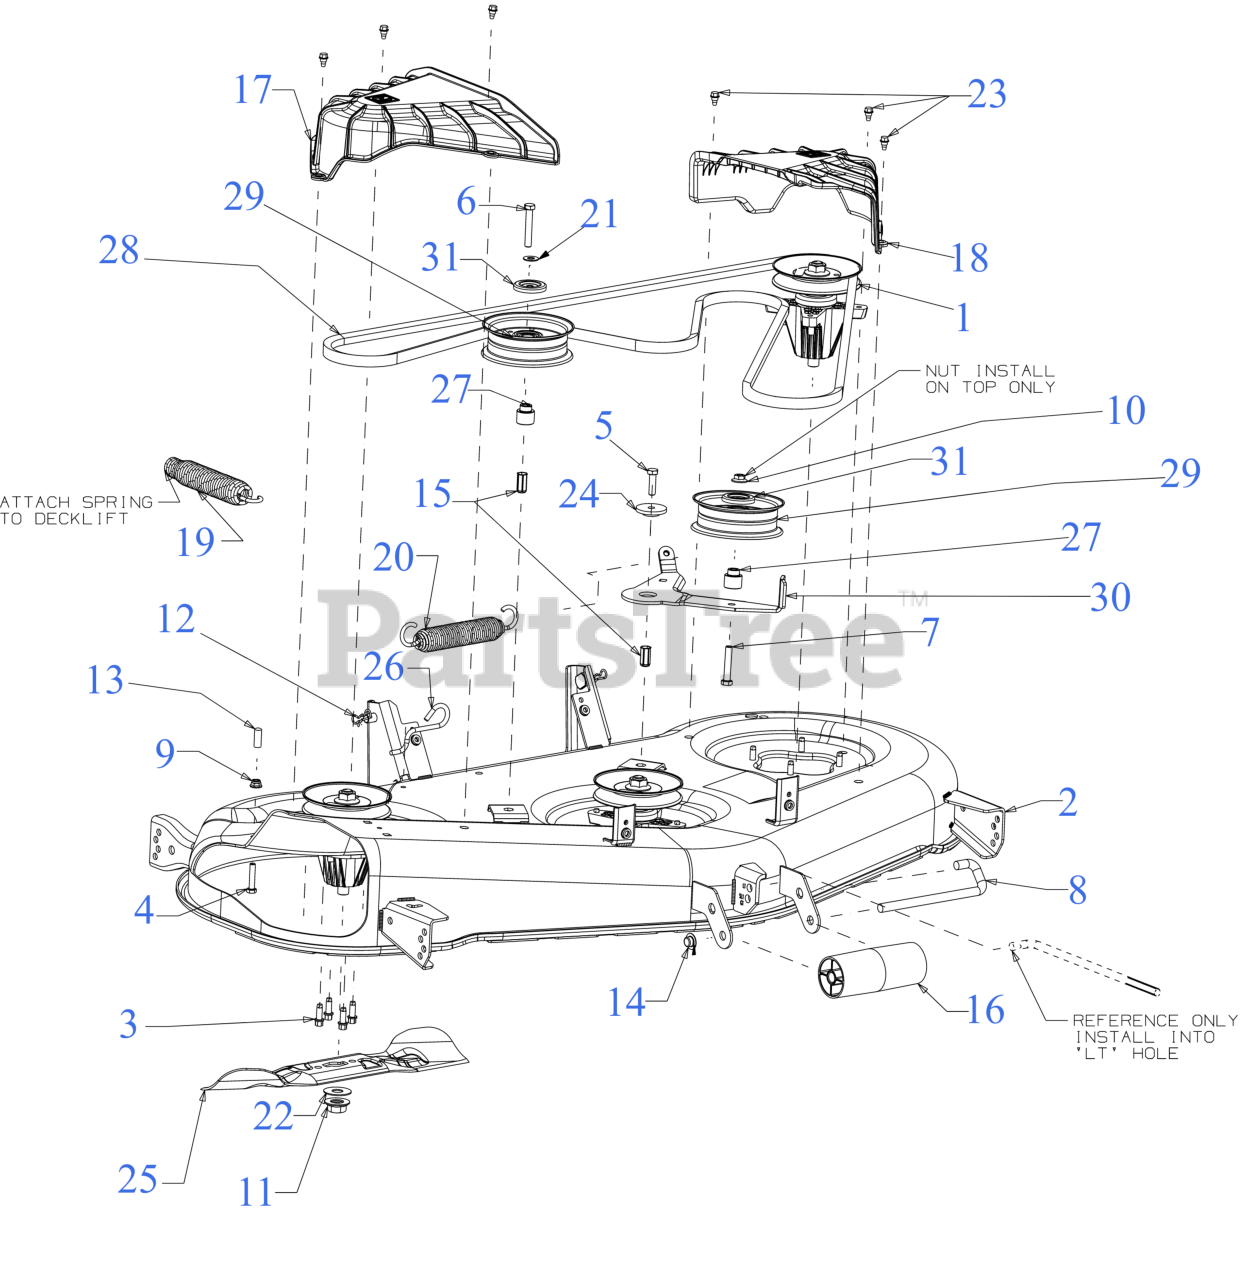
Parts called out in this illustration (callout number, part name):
1	SPINDLE ASSEMBLY (5.37 DIA)
2	50" DECK SHELL
3	SCREW 5/16-18 x .875
4	SCREW 5/16-18 x 1.5 LG
5	SCREW 3/8-16 x 1.25 GR5
6	SCREW 3/8-16 x 2.25 GR5
7	SCREW 3/8-16 x 2.0 GR 8
8	ROLLER PIN 1/2 x 7.31
9	FLANGE LOCK NUT 5/16-18
10	FLANGE LOCK NUT
11	HEX FLANGE NUT 5/8-18 GR5
12	BOW TIE COTTER PIN
15	NUT RIVET 3/8-16
17	SPINDLE COVER (RH)
18	SPINDLE COVER (LH)
19	LIFT ASSIST SPRING (LARGE)
20	SPRING 1.25" DIA x 8.5" LONG
21	FLAT WASHER .401X.88
22	FLAT WASHER .635X1.585X.062 HDN
23	SHOULDER SCREW 1/4-20 x .50
24	SHOULDER SPACER
25	17.271" BLADE (2IN1) (S SHAPE CENTER HOLE)
25	Cub Cadet 50" HI LIFT BLADE SET (S SHAPE CENTER HOLE) (-05094)
25	17.271" XTREME BLADE (2IN1) (S SHAPE CENTER HOLE)
25	Cub Cadet 50" XTREME BLADE SET (S SHAPE CENTER HOLE) (-05094-X)
25	17.271" LOW LIFT (S SHAPE CENTER HOLE)
25	Cub Cadet 50" LOW LIFT BLADE SET (S SHAPE CENTER HOLE) (-05094-X)
26	DECK SPRING HOOK
27	SHOULDER SPACER
28	V-BELT B SEC x 134
28	Cub Cadet 50" DECK BELT
28	Genuine Factory Parts 50" DECK BELT
29	IDLER PULLEY 4.50" DIA
30	IDLER PIVOT BRACKET
31	IDLER PULLEY CAP
